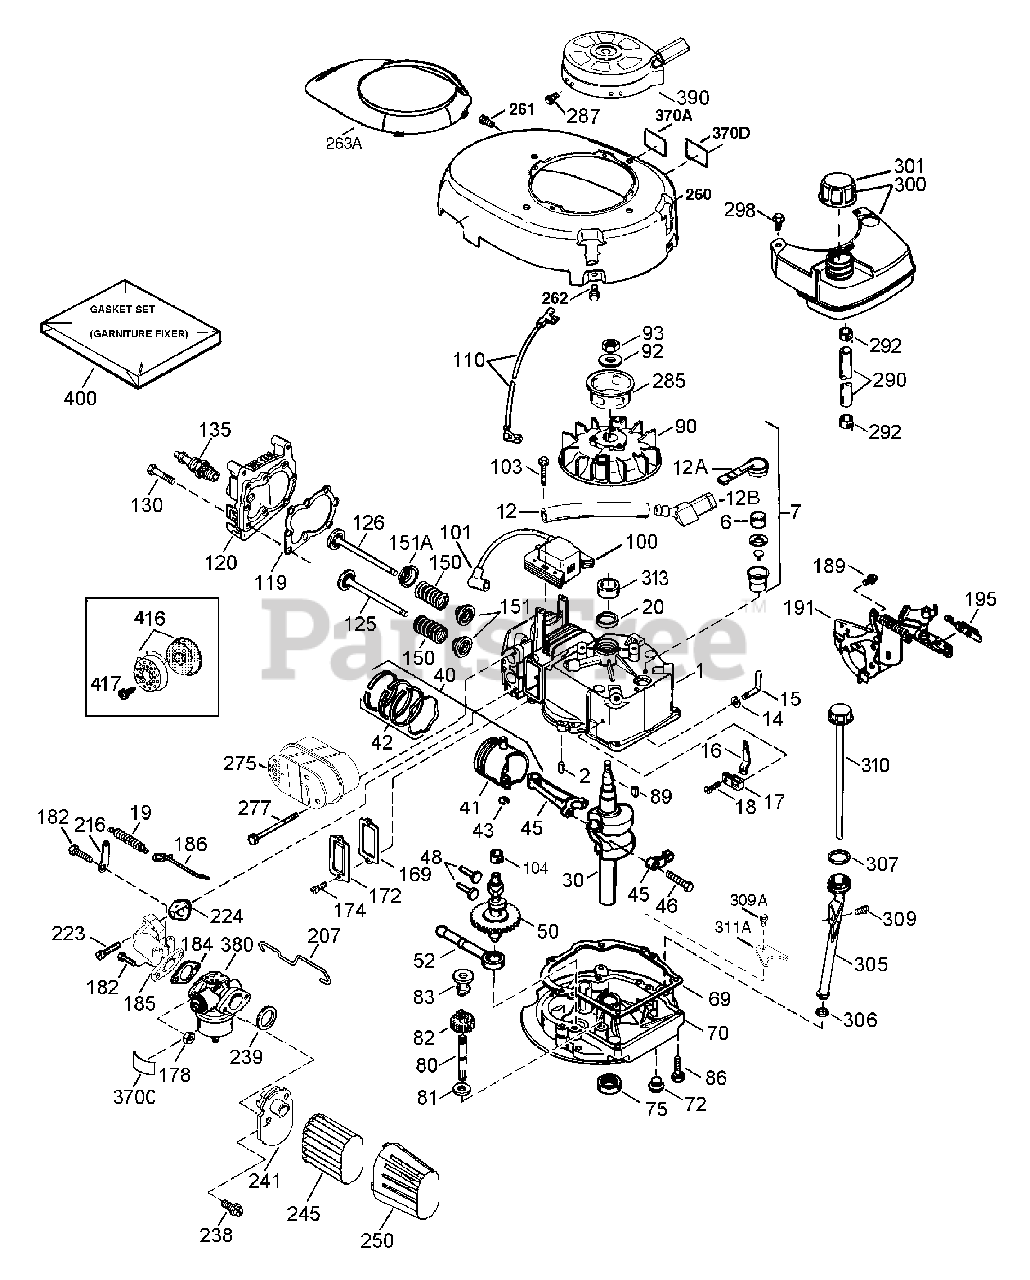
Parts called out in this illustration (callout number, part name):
313	Spacer
370A	Lubrication Decal
370C	Primer Decal (3X)
370D	Caution Decal
380	Carburetor (Incl. 184)
390	Rewind Starter (NOTE: This engine could have been built with 590694 starter.)
400	Gasket Set
416	Spark Arrestor Kit (Incl. 417)(Optional)
417	Screw, 8-32 x 3/8' (Optional)
